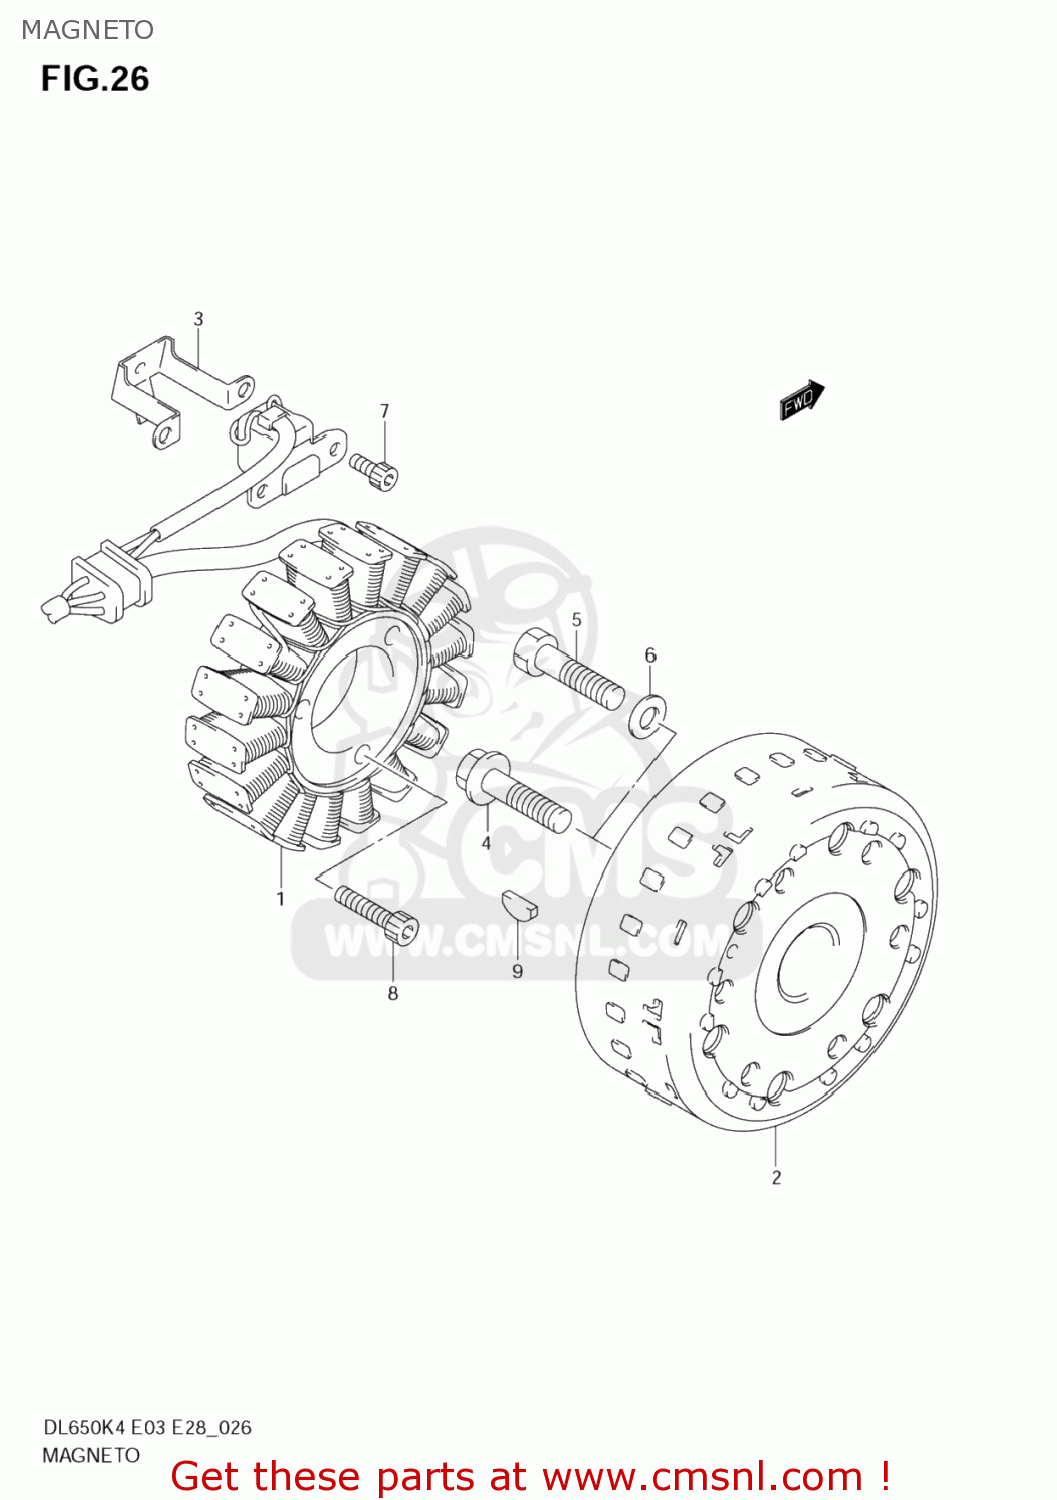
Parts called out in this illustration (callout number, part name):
1	STATOR ASSY
2	ROTOR ASSY
3	CLAMP,MAGNETO LEAD
4	BOLT,MAGNETO ROTOR
5	BOLT(12X40)
6	WASHER(12X30X3)
7	BOLT
8	BOLT
9	KEY
